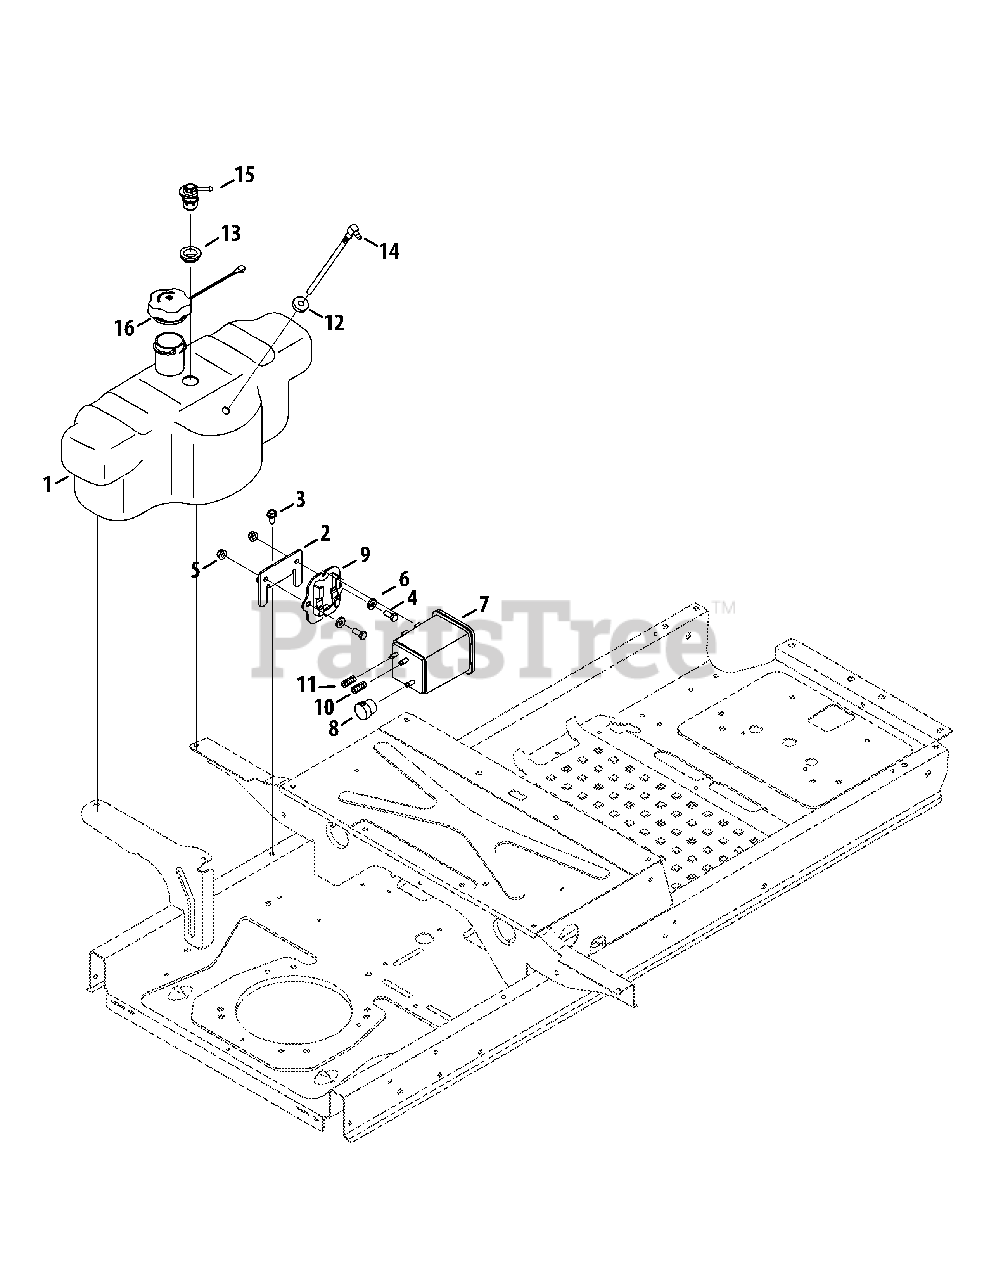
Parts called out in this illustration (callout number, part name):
1	Fuel Tank
2	Carbon Canister Bracket
3	Hex Washer Screw, 5/16-18 x .750
4	Hex Screw, 5/16-18 x .75
5	Flange Lock Nut, 5/16-18
6	Flat Washer, .344 x .750 x .120
7	Carbon Canister
8	Cannister Filter Vent
9	Cannister Adapter Bracket
10	Low Perm Fuel Hose 7/32 Yellow
11	Vent Hose, Carb
12	Fuel Tank Bushing
13	Rubber Grommet
14	Fuel Pickup Fitting
15	Rollover Valve
16	Fuel Cap
